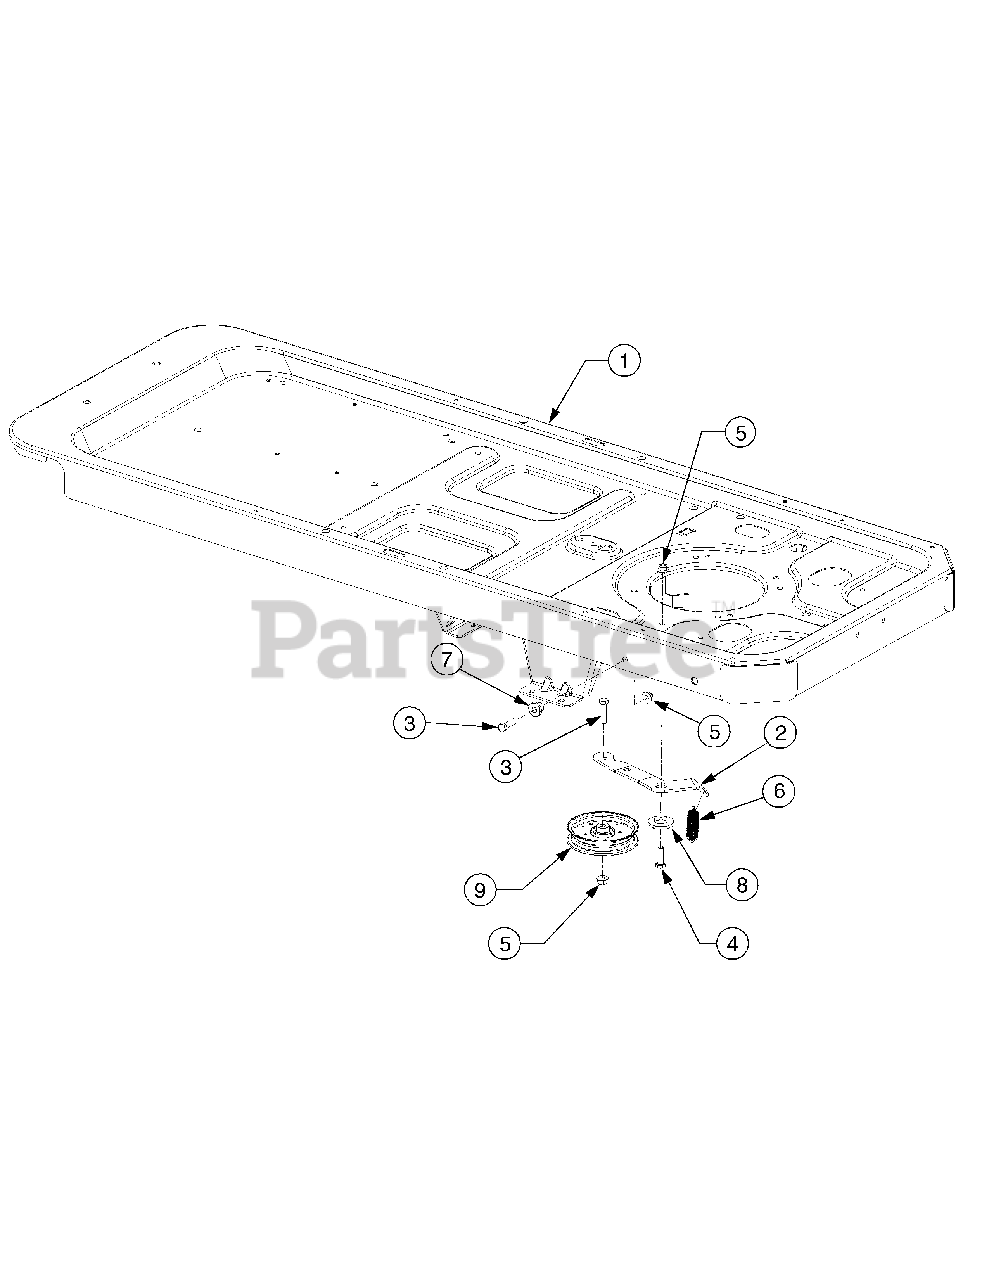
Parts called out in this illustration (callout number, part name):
1	Graphic, Release Lever
3	Screw, Hex Cap, 3/8-16 x 1.5 GR5
4	Screw, Hex Cap, 3/8-16 x 1.25 GR5
5	Nut, Hx Insert Flange Lck, 3/-16 GRF
6	Spring, Extension, .75 x 5.06
7	Spacer, Shoulder, .39 x 1.0 x .7
8	Screw, Shoulder, .884 x .19
9	Pulley, Idler, 4.25 Dia.
